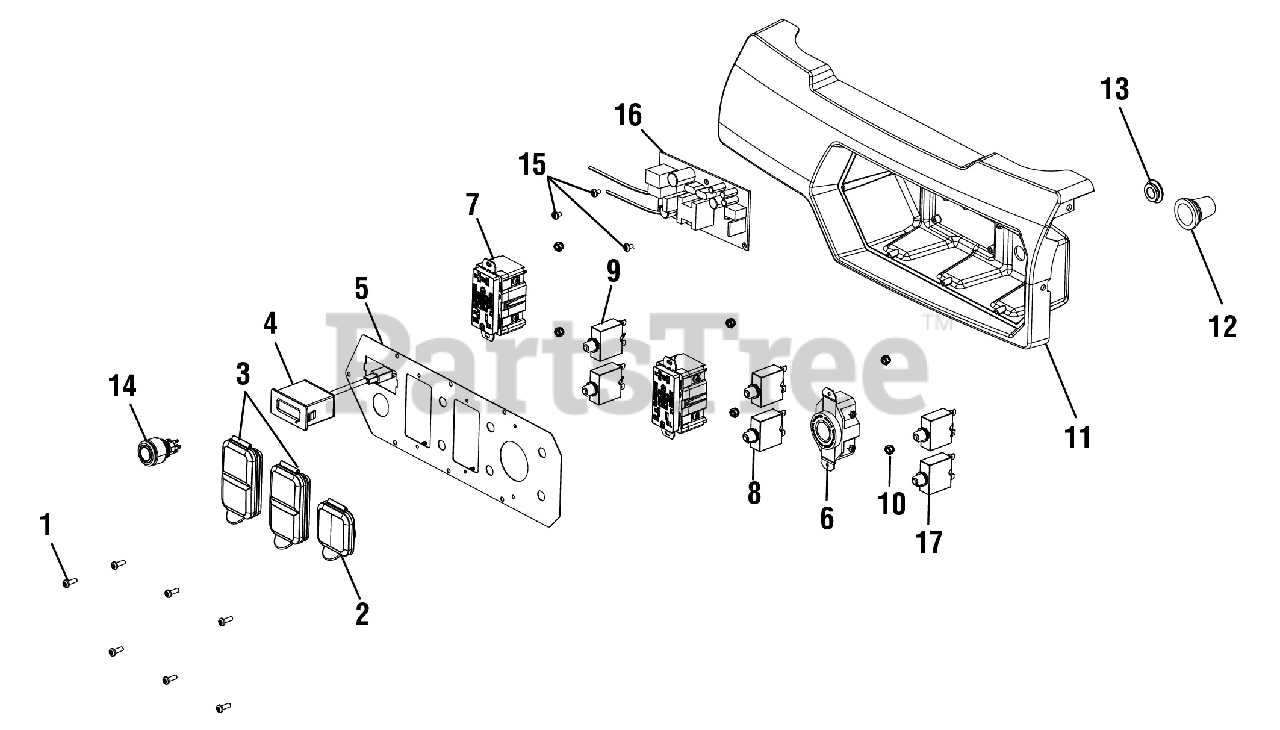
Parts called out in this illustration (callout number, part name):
1	Screw (#8-18 x 1/2 in., T20 Torx Pan Hd.)
2	240 Volt ReceptacleRain Cover
3	120 Volt Receptacle Rain Cover
4	Digital Display
5	Front Panel
6	Twist Lock Recepticle (120/240 Volt, 30 Amp, L14-30)
7	Duplex Receptacle (120 Volt)
8	Circuit Breaker (30A)
9	Circuit Breaker (20 Amp)
10	Lock Nut (M4)
11	Control Box (Back Panel)
12	Wiring Rubber Boot
14	Engine Start Push Switch
15	Screw (M3 x 5 mm, T10 Torx Pan Hd.)
16	Battery Charger
17	Circuit Breaker (33 Amp)
